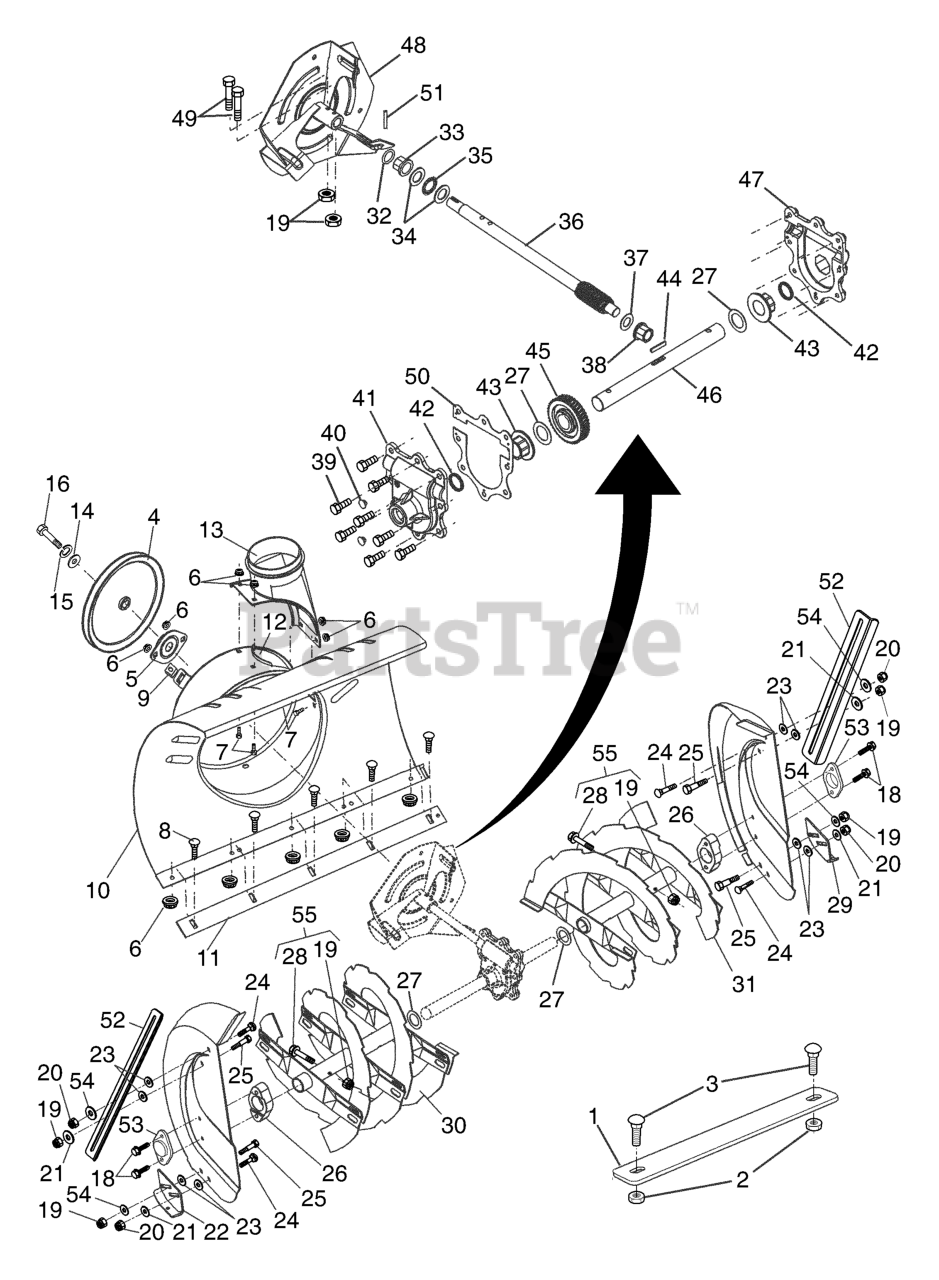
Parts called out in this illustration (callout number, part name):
1	WEIGHT, AUGER HOUSING 27
2	LOCKNUT 5/16-18
3	BOLT.CARRIAGE.5/16-18
4	PULLEY, IMPELLER
5	BEARING FLANGE
6	NUT.FLANGE.5/16
7	BOLT.CARRIAGE.5/16-18X
8	BOLT
9	NUT, CAGE 3/8-16
10	HOUSING, AUGER
11	BAR, SCRAPER 30"
12	BRACKET, CORNER DISCHARGE
13	BASE DISCHARGE CHUTE
14	WASHER, FLAT
15	WASHER.LOCK.HVY.HLCL.SPR.5/16
16	Screw, Hex Head 5/16-18 x 3/4
18	SCREW, HEX HD 5/16X1
19	LOCKNUT.NYLOC.1/4-20
20	NUT.71038.31-18.HEX.NYLOCK
21	WASHER.20X8.5
22	SKID PLATE RH
23	WASHER, NYLON FRICTION
24	BOLT
25	SHOULDER BOLT
26	BEARING RETAINER, PLASTIC
27	WASHER TRUST 1"
28	KIT, SHEAR BOLT
29	SKID PLATE LH
30	AUGER ASSY, RH
31	AUGER ASSY, LH
33	BUSHING FLANGE 3/4
34	WASHER, THRUST 3/4
35	BEARING TRUST 3/4 NTA-1220
36	SHAFT, IMPELLER
37	WASHER, THRUST 5/8
38	BUSHING.FLANGE.(.625X.75)
39	SELF-TAPPING SCREW 5/16-18X3/4
40	PLUG.AUGER.GEAR.BOX.SNOW
41	HOUSING.GEARBOX.RH.SNOW
43	BUSHING FLANGE 1"
44	KEY
45	WORM GEAR
46	SHAFT, AUGER
47	LH GEARBOX HOUSING
48	IMPELLER ASSY
49	SCREW.HEX.HD1/4-20X
50	GASKET.AUGER.GEARBOX
51	PIN, ROLL 3/16 X 1-1/8
52	DRIFT CUTTER BAR
53	BEARING.BALL.AUGER.SHAFT
54	WASHER
55	KIT, BOLT, SHEAR
